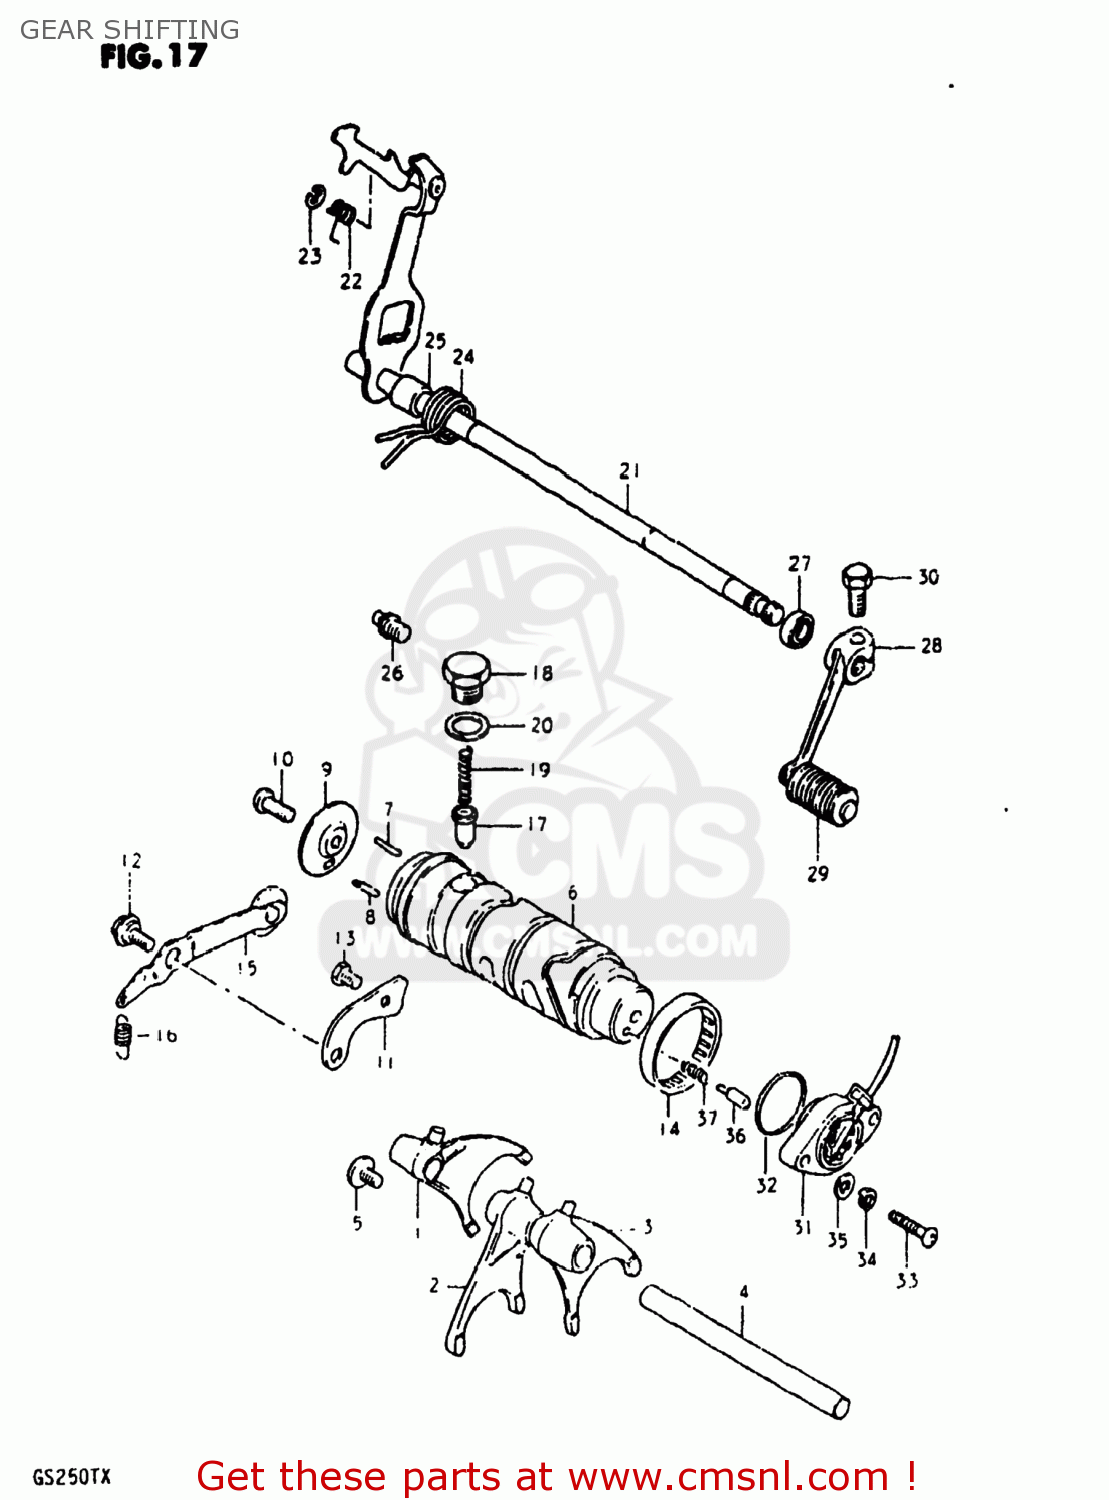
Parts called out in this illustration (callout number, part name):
1	FORK,GEAR SHIFT NO.1
2	FORK,GEAR SHIFT NO.2
3	FORK,GEAR SHIFT NO.3
4	SHAFT,GEAR SHIFT FORK
5	SCREW
6	CAM,GEAR SHIFT
7	PIN(4X18.5)
8	PIN
9	RETAINER,GEAR SHIFT CAM DR PIN
10	SCREW
11	GUIDE,GEAR SHIFTING CABLE
12	BOLT
13	BOLT, UPPER
14	BEARING(40X47X12)
15	STOPPER,GEAR SHIFTING
16	SPRING
17	STOPPER,GEAR SHIFT CAM NO.2
18	HOLDER,GEAR SHIFT CAM STOP SPR
19	SPRING
20	GASKET(14X19.2X2) (NAS)
21	SHAFT,GEAR SHIFT
22	SPRING
23	E RING
24	SPRING
25	SPACER(12X20X15.3)
26	STOPPER,GEAR SHIFT CAM
27	OIL SEAL
28	LEVER ASSEMBLY,GEAR SHIFTING
29	RUBBER,GEAR SHIFT PEDAL
30	BOLT
31	TERMINAL BASE,NEUTRAL SWITCH
32	O-RING (D:2.4 ID:26.2)
33	SCREW 5X20
34	LOCK WASHER
35	WASHER
36	PIN(5X15.5)
37	SPRING
